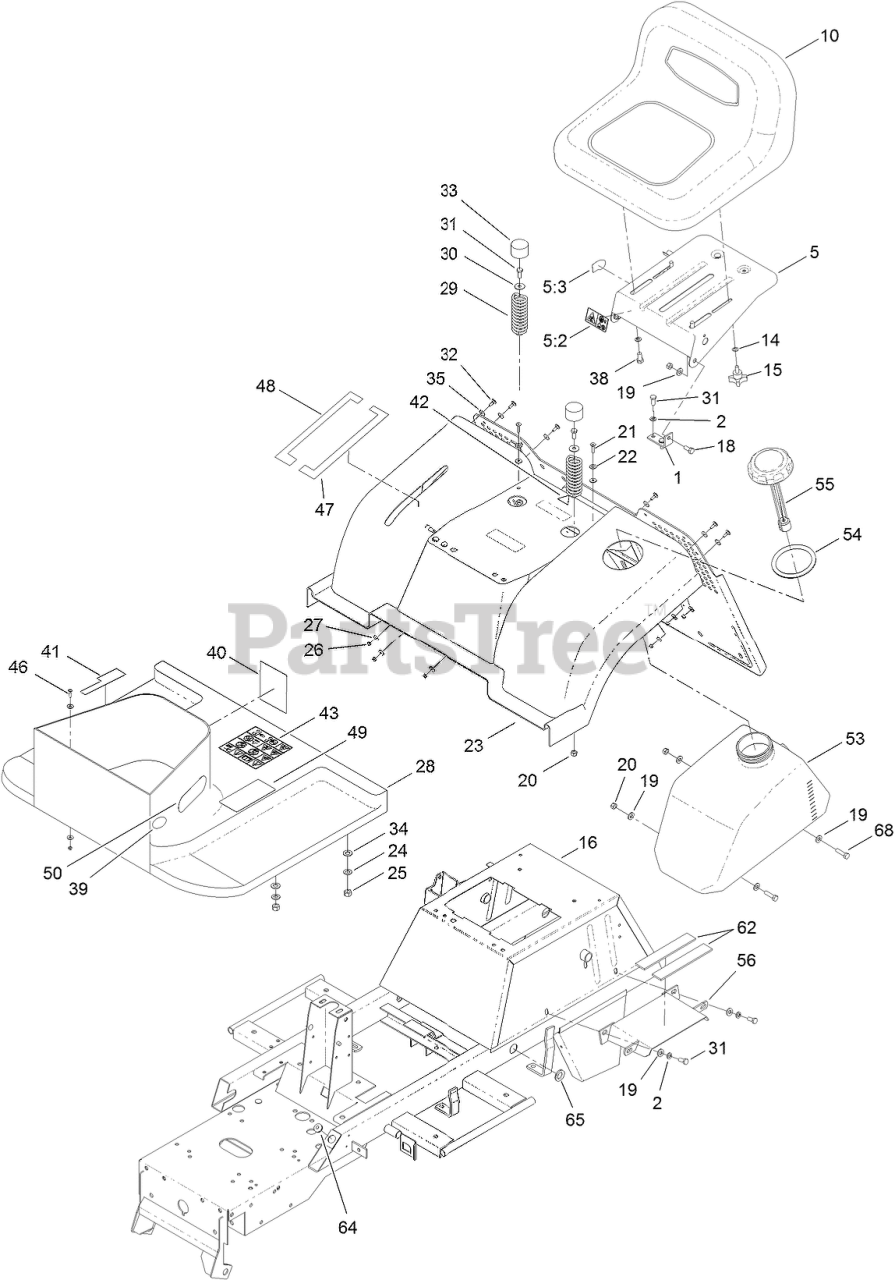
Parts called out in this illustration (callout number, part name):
1	BRACKET-SUPPORT, SEAT
2	WASHER-LOCK
5	SEAT PAN ASM
5:2	DECAL-DANGER
5:3	DECAL-SWITCH
10	SEAT ASM
14	WASHER-SPRING
15	KNOB-ADJUST
16	FRAME KIT
18	SCREW-SUPPORT, SEAT
19	WASHER-PLAIN
20	NUT-LOCK, NI
21	SCREW-HSFH
22	WASHER-FINISH
23	FENDER-REAR
24	WASHER-FLAT
25	NUT-LOCK, NI
26	NUT-LOCK
27	WASHER-FLAT
28	FOOTREST ASM
29	SPRING-SEAT
30	WASHER-PLAIN
31	SCREW-HH
32	BOLT-CARRIAGE
33	CAP-HUB
34	WASHER-RUBBER
35	WASHER-RUBBER
38	SCREW-HHF
39	DECAL-BRAKE, PARKING
40	DECAL-STARTING
41	DECAL-OPERATION, HYDRO
42	DECAL-BAG TO FRAME
43	DECAL-DANGER
46	SCREW-HH
47	DECAL-HOC, LH
48	DECAL-HOC, RH
49	DECAL-OPERATION
50	DECAL-TOWER
53	TANK-FUEL
54	PROTECTOR-NECK, FILLER
55	CAP-FUEL
56	BRACKET-TANK, FUEL
62	STRIP-RUBBER, FUEL TANK
64	GROMMET
65	GROMMET
68	SCREW-HH
